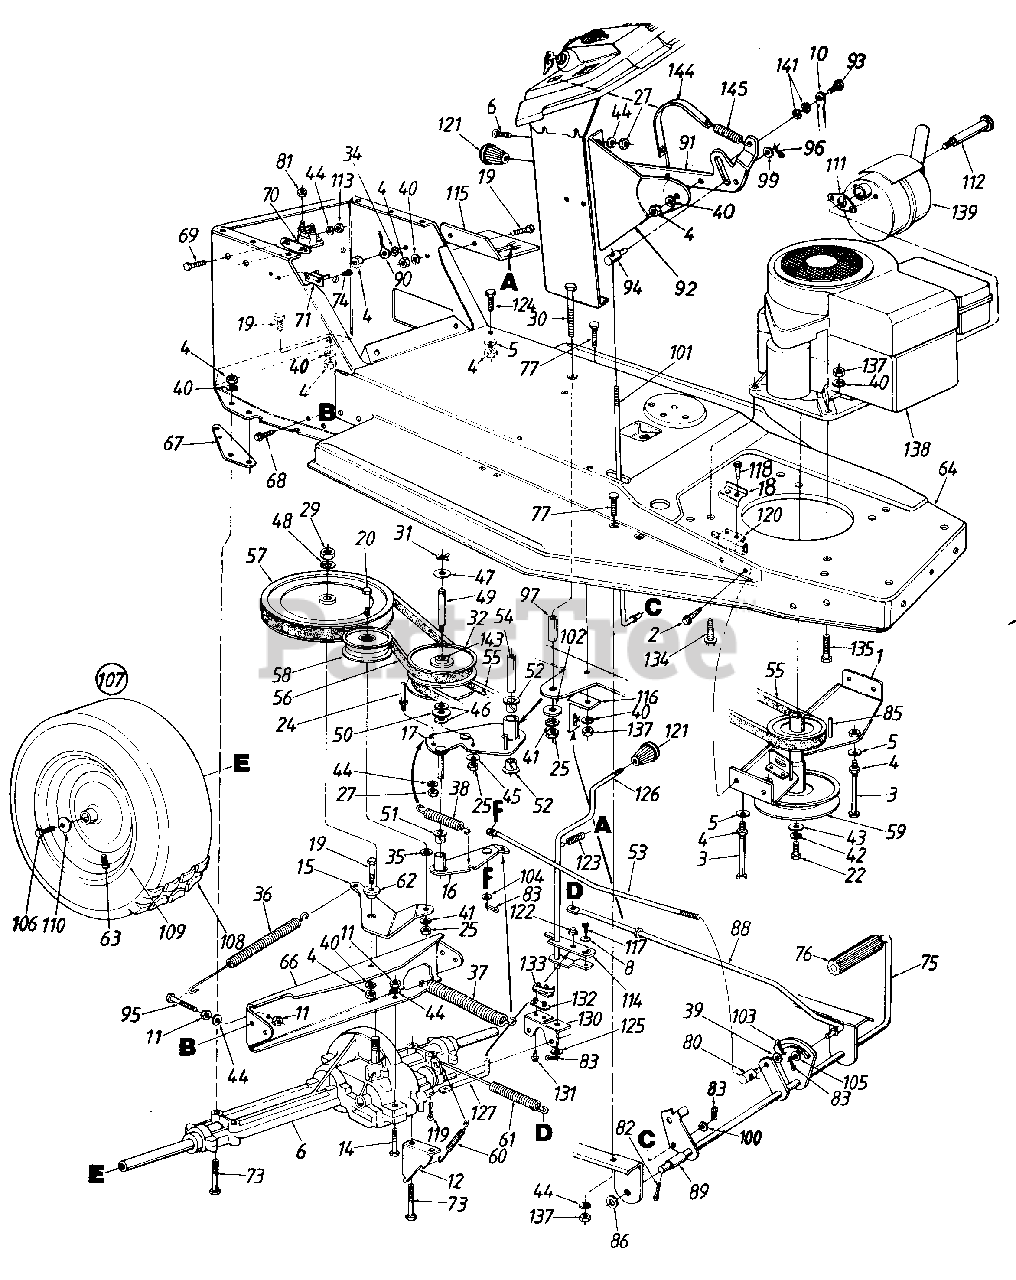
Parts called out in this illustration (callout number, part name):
1	Engine Pulley Belt Guard Ass'y.
2	Hex AB-Tap Scr. 1/4 x .62"
3	Hex Bolt 5/16-18 x 5-1/4" Lg.
4	Hex Nut 5/16-18 Thd.
5	Bell-Wash. .345" I.D. x .88
6	Truss-Mach. Scr. 1/4-20 x .50"
8	Bell-Wash. .265" I.D. x .75
10	Speed Selector Brace
11	Hex Nut 1/4-28 Thd.
12	Spring Retainer Brkt.
14	Hex Bolt 1/4-28 x 1.75" Lg.
17	Variable Speed Brkt. Ass'y.
18	Switch Plate
19	Hex Bolt 5/16-18 x .75" Lg.
20	Hex Bolt 3/8-24 x 2.0" Lg. Grade 5
22	Hex Bolt 7/16-20 x 1.5" Lg.
24	Belt Guard Pin
25	Hex Nut 3/8-24 Thd.
27	Hex Nut 1/4-20 Thd.
29	Hex Jam Nut 1/2-20 Thd.
30	Hex Bolt 3/8-24 x 3.75" Lg.
31	Snap Ring
32	Variable Speed Pulley Ass'y.
34	Ext. L-Wash. 5/16" I.D.
35	Fl-Wash. 3/8" I.D. x 1.0" O.D.
36	Extension Spring 6.12" Lg.
37	Extension Spring 7.5" Lg.
38	Extension Spring 2.59" Lg.
39	Fl-Wash. .385" I.D. x .620"
40	L-Wash. 5/16" I.D.
41	L-Wash. 3/8" I.D.
42	L-Wash. 7/16" I.D.
43	Fl-Wash. .450" I.D. x 1.25"
44	L-Wash. 1/4" I.D.
45	Bell-Wash. .39" I.D. x 1.13"
46	Fl-Wash. .56" I.D. x 1.0" O.D.
47	Washer "Teflon" .565 I.D.
48	Bell-Wash. 1/2" I.D. x 1.0" O.D.
49	Shaft .56" Dia. x 3.875" Lg.
50	Thrust Brg. 1.25 O.D.
51	Flanged Nyliner Brg.
52	Nyliner Flanged Brg.
53	Speed Control Rod
54	Spacer
55	V-Belt
56	V-Belt
57	1/2 V-Pulley x 8" Dia.
58	Idler Pulley 3-1/8" Dia.
59	Dbl. Pulley 6.0" Dia. x 3.56"
60	Extension Spring 3.18" Lg.
61	Extension Spring 7.08" Lg.
62	Shld. Spacer .500" Dia.
63	Air Valve
66	Transaxle Support Brkt.
69	Hex Bolt 1/4-20 x .62" Lg.
70	Solenoid
71	Circuit Breaker
73	Hex Bolt 5/16-18 x 2.75" Lg.
74	Truss Mach. B-Tap Scr. #10 x.50" Lg.
75	Foot Pedal Rod Ass'y.
76	Foot Pad
77	Ribbed Neck Bolt 5/16-24 x .84"
80	Ferrule
81	Hex Sems Nut 1/4-20 Thd.
82	Cot-Pin 1/8" Dia. x 1.25" Lg.
83	Cot-Pin 3/32" Dia. x .75" Lg.
85	Sq. Key 1/4 x 2.0" Lg.
86	Fl-Wash. .635" I.D. x 1.0"
88	Brake Rod
89	Spacer 5/8" I.D. x 1.2" Lg.
90	Ground Wire 7.25" Lg.
91	Speed Selector Lever
92	5 Speed Selector Brkt.
93	Shld. Bolt .437" Dia. x .47" Lg.
94	Ferrule
95	Hex Bolt 1/4-28 x 1.25" Lg.
96	Intern. Cot-Pin 5/16" Dia.
97	Spacer .375" I.D. x .625"
99	Fl-Wash. .344" I.D. x .62"
100	Fl-Wash. .25" I.D. x .62" O.D.
101	Speed Control Rod
102	Fl-Wash. 3/8" I.D. x .1" O.D.
103	Cot-Pin 1/8" Dia. x 1.0" Lg.
104	Fl-Wash. .34" I.D. x .68"
105	Fl-Wash. .34" I.D.
106	Hex L-Bolt 5/16-24 x .75" Lg.
110	Bell-Wash. .345" I.D. x .88"
111	Exhaust Gasket
112	Shld. Bolt 7/16" Dia. x 3-5/8" Lg.
113	Hex Jam Nut 1/4-20 Thd.
114	Shift Lever Adjusting Link
115	Shift Lever Spring Brkt.
118	Hex Wash. Hd. Tap Scr. 1/4-20 x .5" Lg.
119	Intern. Cotter Pin
120	Safety Switch
121	Knob
122	Retaining Ring
123	Compression Spring 1.5" Lg.
124	Hex Wash. Hd. Scr. 5/16-18 x .62" Lg.
125	Fl-Wash. .469" I.D. x .88"
130	Shift Lever Support
131	Hex Wash. Hd. #8 x .50" Lg.
132	Insulator Nut Plate
133	Spring Switch
134	Hex Tap Scr. 3/8-16 x 1.25"
135	Hex Bolt 5/16-24 x 1-1/4" Lg. Grade 5
137	Hex Nut 5/16-24 Thd.
138	Engine
139	Muffler
141	Wave Wash. .445" I.D.
143	Needle Brg.
144	Speed Indicator Strip
145	Ext. Spring 2.04" Lg.
